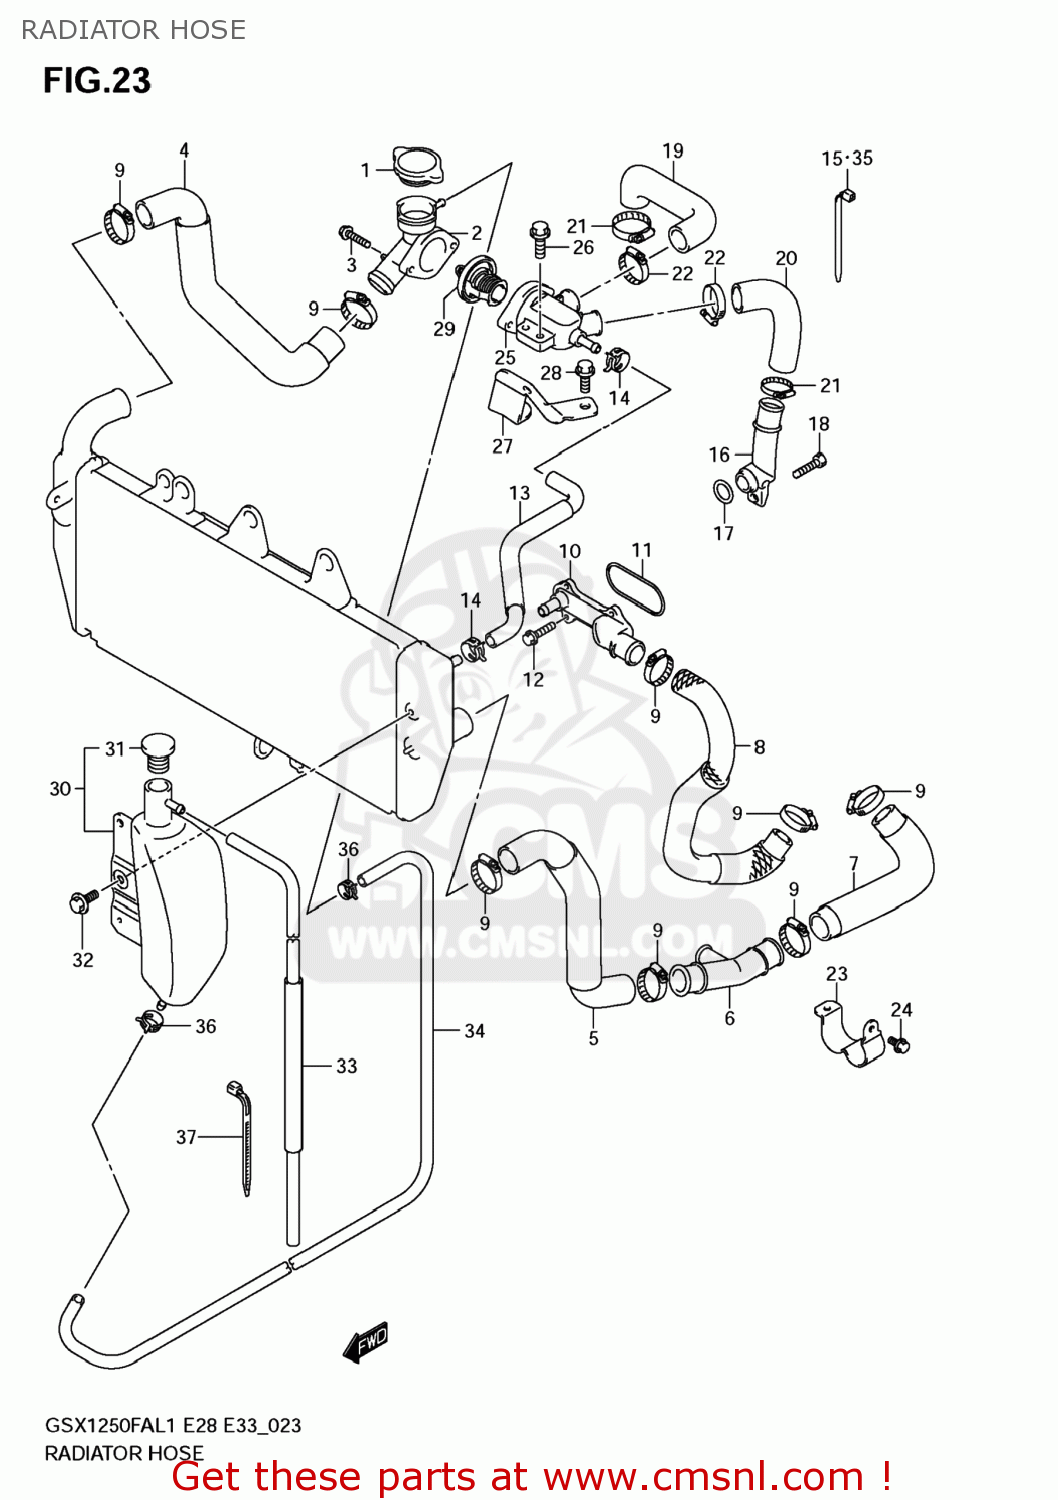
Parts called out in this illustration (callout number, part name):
1	CAP,RADIATOR(1.1)
2	CONDUCTION,RADIATOR
3	BOLT
4	HOSE,RADIATOR INLET
5	HOSE,RADIATOR OUTLET
6	PIPE,RADIATOR OUTLET
7	HOSE,WATER PUMP INLET
8	HOSE,WATER PUMP OUTLET
9	CLAMP
10	CONNECTOR,CYLINDER WATER INLET
11	O RING,CYL INLET CONNECTOR
12	BOLT
13	HOSE,WATER BYPASS
14	CLAMP
15	CLAMP(L:165)
16	PIPE,CYLINDER HEAD OUTLET
17	O RING(D:3.2,ID:17.8)
18	BOLT
19	HOSE,CYLINDER HEAD OUTLET,R
20	HOSE,CYLINDER HEAD OUTLET,L
21	CLAMP
22	CLAMP
23	PLATE,WATER HOSE CLAMP
24	BOLT
25	CONNECTOR,THERMOSTAT INLET
26	BOLT
27	BRACKET,THERMOSTAT CONNECTOR
28	BOLT
29	THERMOSTAT,WATER 82 DEG
30	TANK ASSY,RESERVOIR
31	CAP,RESERVOIR TANK
32	BOLT(6X12)
33	HOSE,RESERVOIR TANK OVFL
34	HOSE(5X9X2000)
35	CLAMP(L:165)
36	CLIP
37	CLAMP(L:235)
